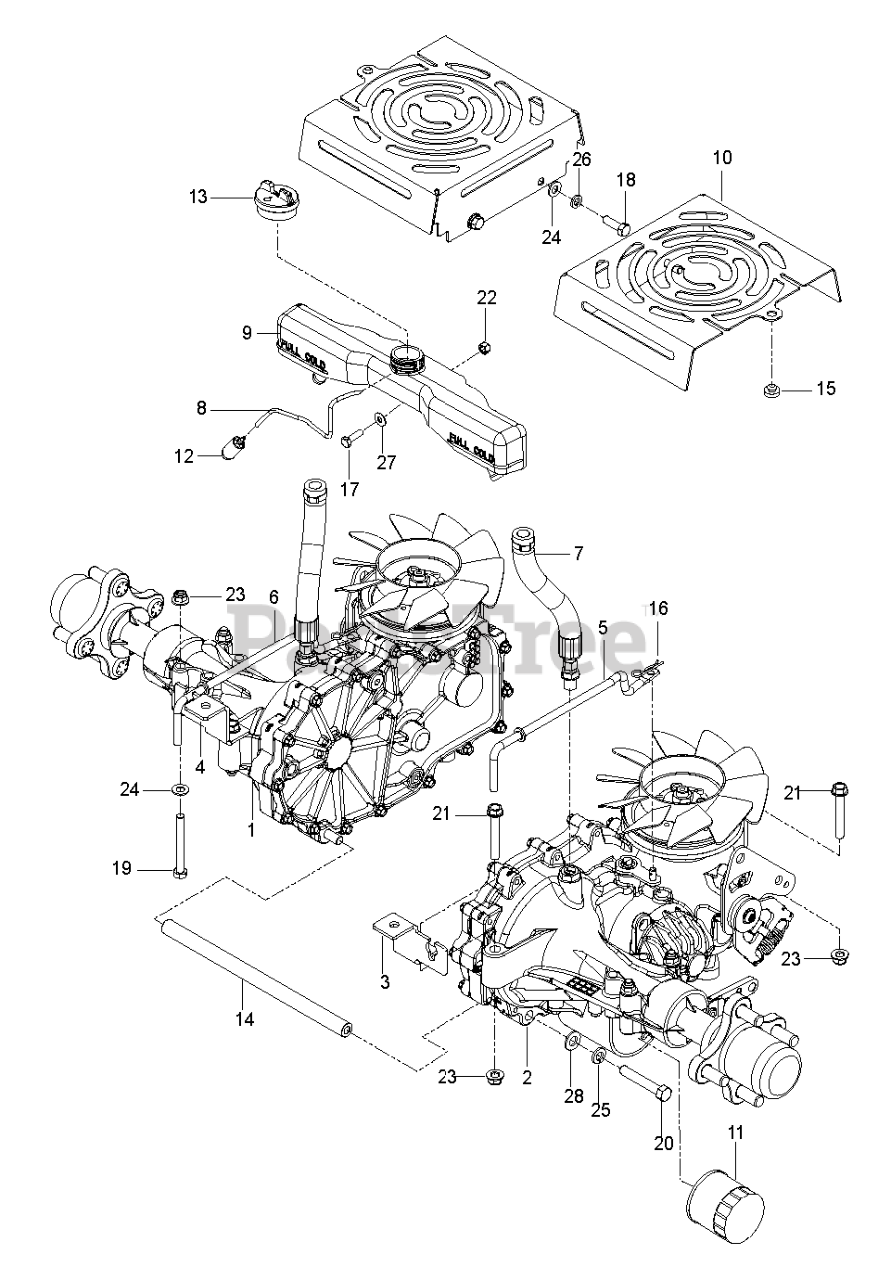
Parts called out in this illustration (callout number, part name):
1	HG_TRANS, ZT-3400, LT
2	HG_TRANS, ZT-3400, RT
3	BRACKET.TRANS.LT.BLACK
3	BRACKET TRANS, RT BLACK MS-431
4	BRACKET, TRANS, RT BLACK
4	BRACKET TRANS, LT BLACK MS-431
5	LINKAGE, LEFT BYPASS
6	LINKAGE, RIGHT BYPASS
7	HOSE ASSY, EXPANSION
9	TANK EXPANSION W/CAP
10	SHIELD FAN BLACK
11	HG_FILTER, ZT4800 52114
12	FUEL PICK-UP ASSY
13	CAP EXPANSION W/SEAL
14	HAIRPIN #2
15	GROMMET, BUMPER
16	HAIRPIN #2
17	HCS 1/4-20X7/8 GR5
18	HCS 5/16C X 1
19	NUT.1/4-20.HEX.NYLOC.ZD
19	HCS 5/16C X 2-3/4
20	5/16-18 NYLOC FLANGE NUT
21	HHFS 5/16-18 X 2.25 GD 5
22	SLW 3/8 STD
23	5/16-18 NYLOC FLANGE NUT
24	WASHER
24	FLAT WASHER 5/16 SAE
25	SLW 3/8 STD
26	WASHER.LOCK.HVY.HLCL.SPR.5/16
27	WASHER 1/4 SAE
28	WASHER 3/8 SAE FLAT
